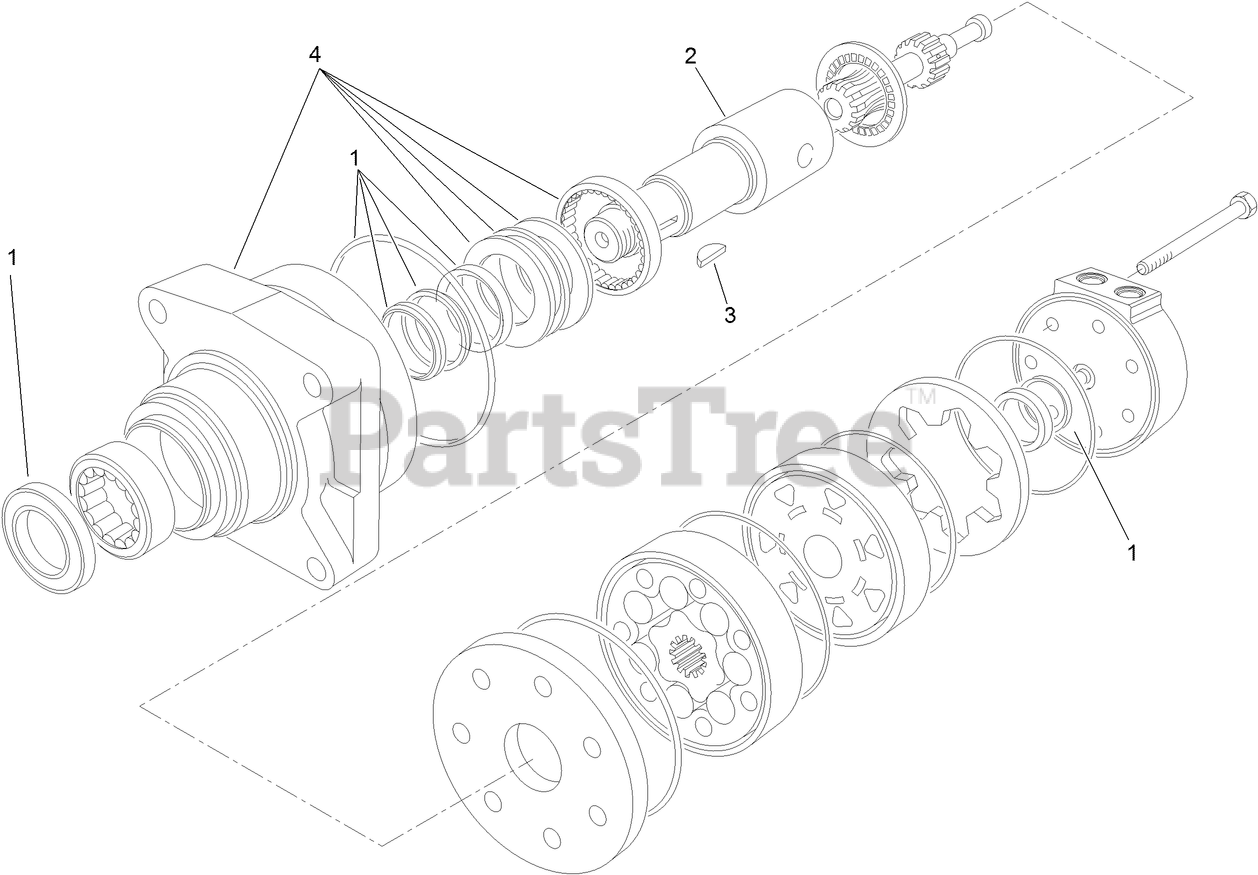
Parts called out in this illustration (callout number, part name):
1	SEAL KIT
2	COUPLING-SHAFT
3	KEY-WOODRUFF
4	MOTOR HOUSING ASM
